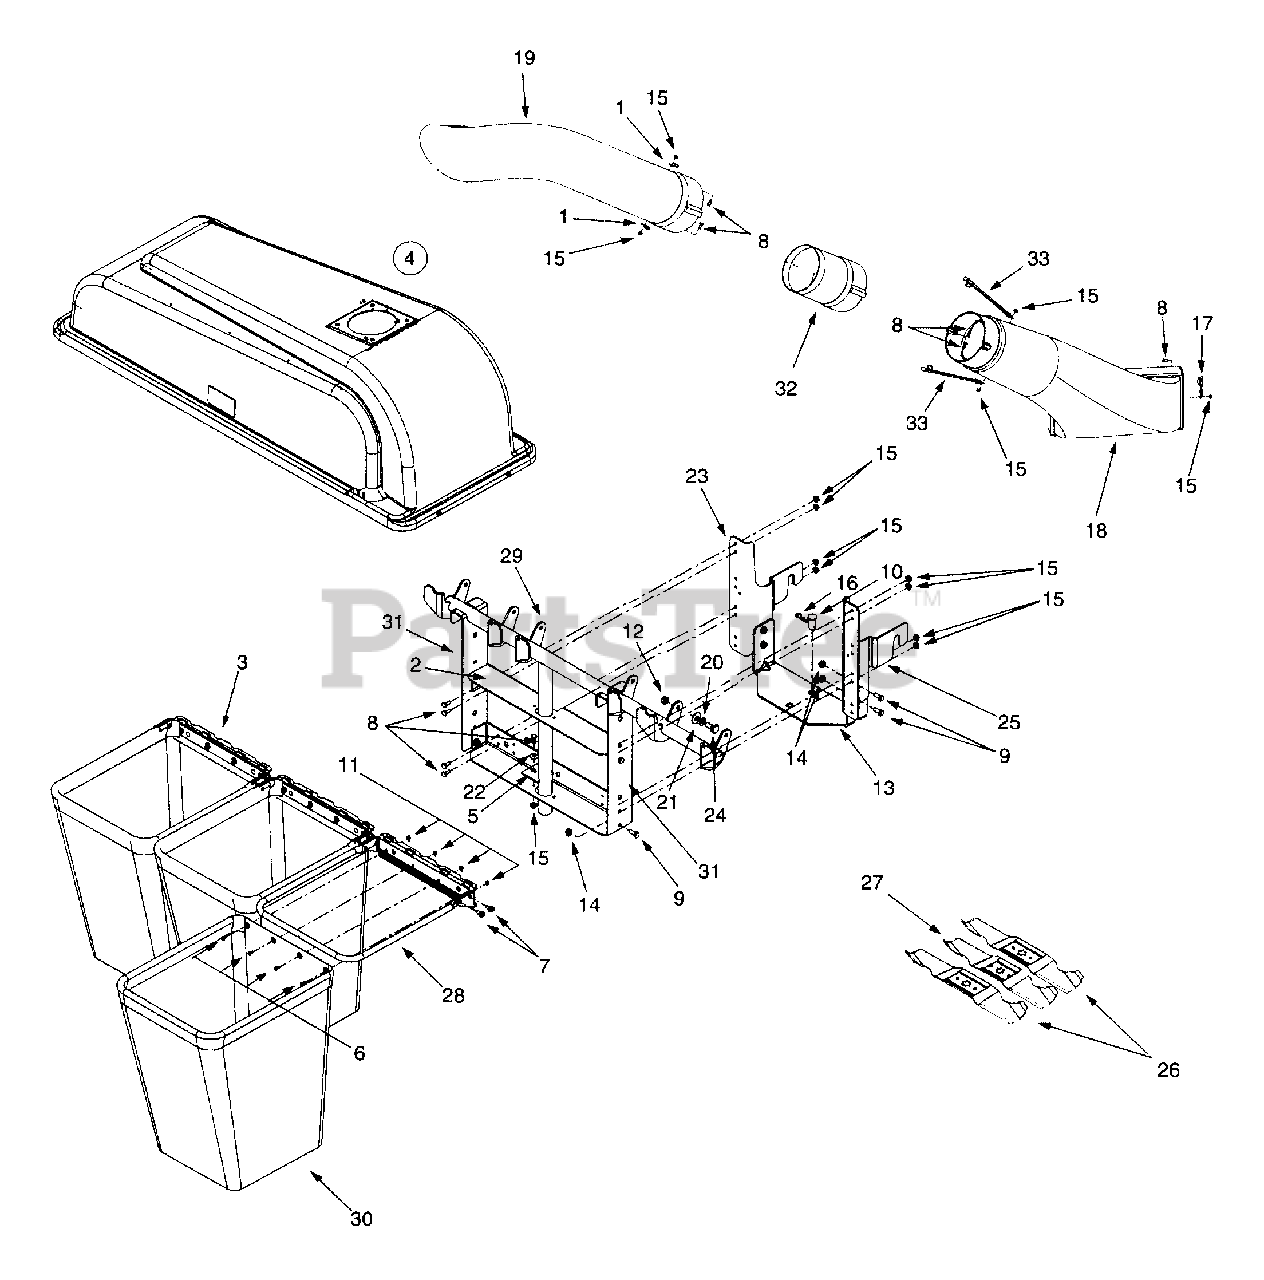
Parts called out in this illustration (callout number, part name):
1	Retainer Hook Bracket
2	Catcher Support Bracket
4	Cover Assembly Complete
6	Screw, #10-24 x .5
7	Self Tapping Screw, 5/16-18 x .625
8	Hex Cap Screw, 1/4-20 x .62
9	Hex Cap Screw, 5/16-18 x .75
10	Clevis Pin
11	Hex Sems Nut, 10-24
12	Hex Flange Lock Nut, 3/8-16
14	Hex Flange Lock Nut, 5/16-18
15	Hex Flange Lock Nut, 1/4-20
16	Internal Cotter Pin, .148 x 3
17	Retainer Strap Assembly
18	Discharge Chute
19	Chute Tube
20	Flat Washer, .51 x .75 x .033
21	Belleville Washer
22	Bell Washer, .265 x .75 x .062
24	Shoulder Screw, .50 x .27, 3/8-16
26	Star-center Blade, 16.28
27	Star-center Blade, 14.88
30	Grassbag
32	Extension Tube
33	Retainer Strap Assembly
